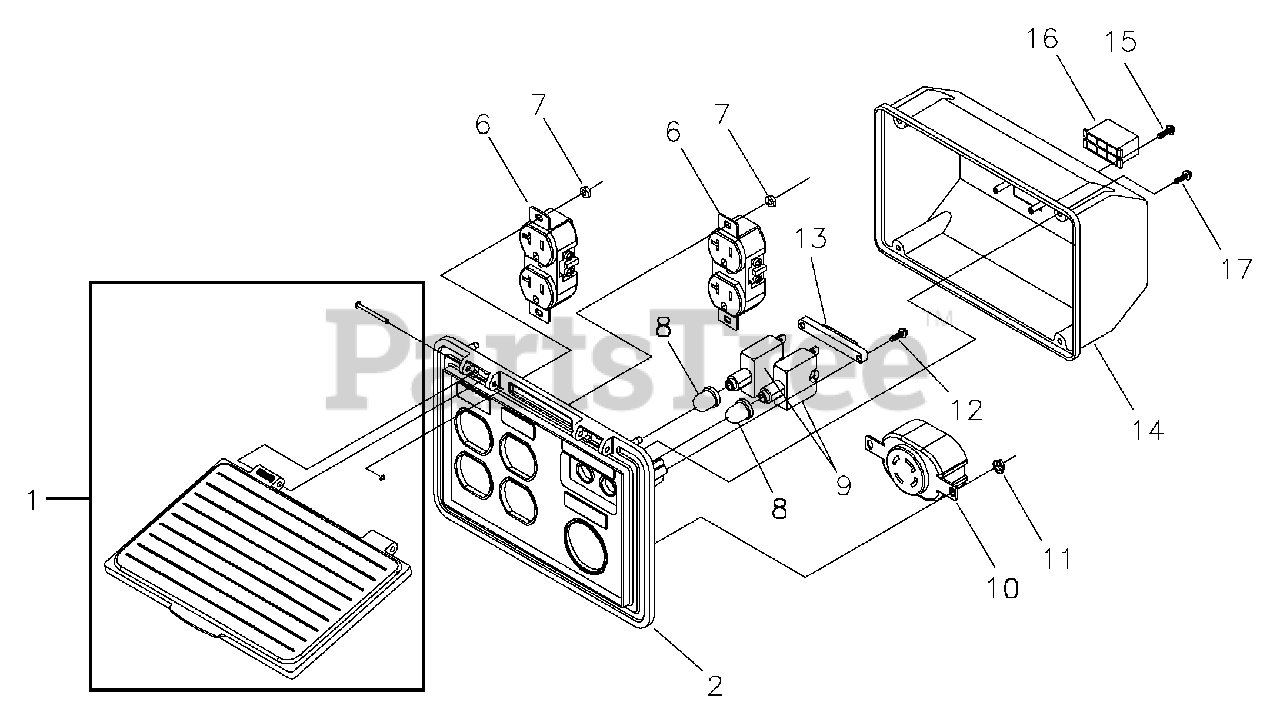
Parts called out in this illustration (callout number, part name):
1	KIT, Control Panel Lid
2	CONTROL PANEL, Compact
6	OUTLET, 120V, 20A, Duplex
8	CAP, Breaker, Circuit
9	BREAKER, Circuit
10	OUTLET, 120/240V Locking, 30A
13	BAR, Retaining
14	COVER, Back, Control Panel
15	SCREW, Self Tapping, STC 3 x 18
16	HOUSING, Receptacle
